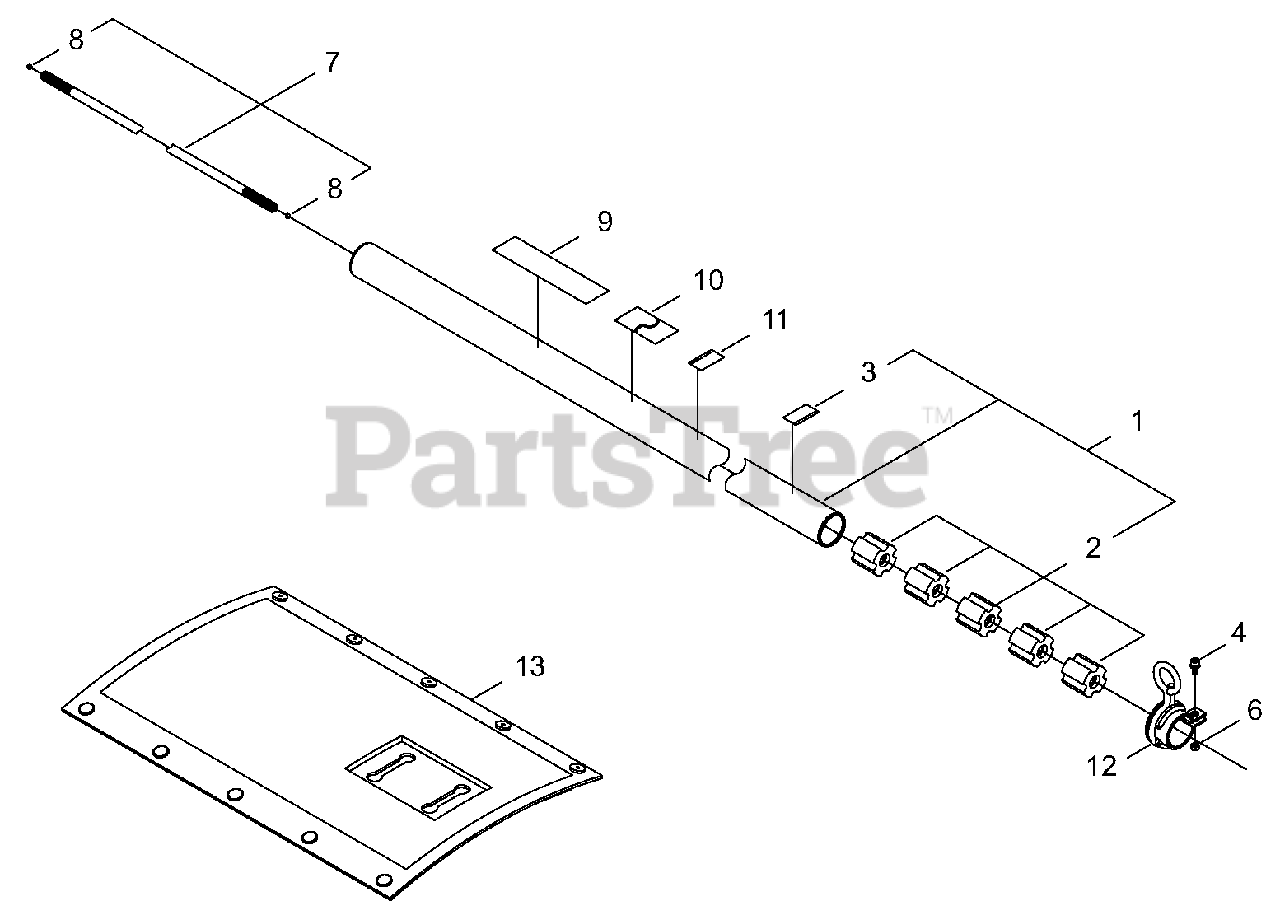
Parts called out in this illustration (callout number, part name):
1	MAIN PIPE ASSY
2	BUSHING
3	LABEL - ALIGNMENT
4	BOLT 5×12
5	WASHER, SPRING 5
6	NUT M5
7	SHAFT ASSY, DRIVE
8	STOPPER
9	LABEL, SHINDAIWA PROFESSIONAL
10	LABEL, CAUTION (BLADE CAPABLE)
11	LABEL, HANDLE
12	HANGER
13	PROTECTOR
